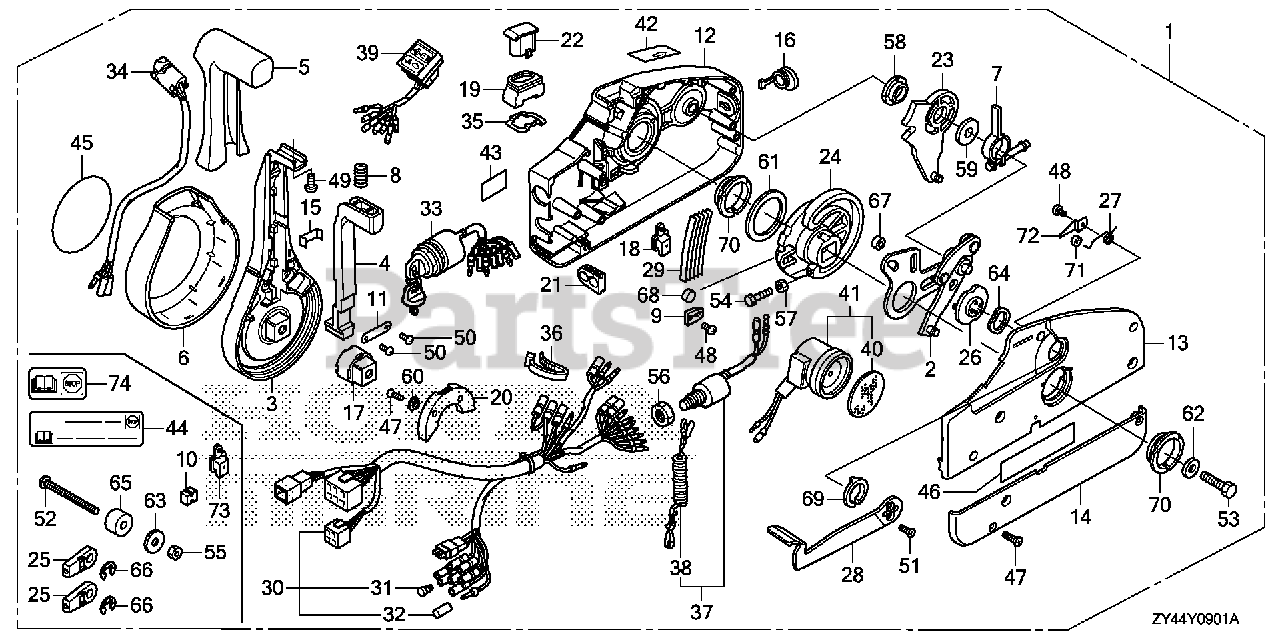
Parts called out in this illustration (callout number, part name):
1	BOX ASSY., REMOTE CONTROL (NHK MEC)
1	BOX ASSY., REMOTE CONTROL (TROLLING CONTROL)(NHK MEC)
2	PLATE ASSY.
3	LEVER, HAND
4	ARM, NEUTRAL LOCK
5	GRIP
6	COVER, LEVER
7	ARM ASSY., BRAKE
8	SPRING (2)
9	CLIP, DETENT
10	SPACER (1) (LOOSE PARTS)
11	BRACKET
12	HOUSING, FR.
13	HOUSING, RR.
14	PANEL, BACK
15	BRACKET, WIRE CLAMP
16	CAP, RUBBER
17	ADJUSTER
18	COVER, POWER TRIM-TILT WIRE
19	SEAL, RUBBER
20	HOLDER, NEUTRAL LOCK
21	GROMMET, WIRE (14)
22	CAP, TROLLING CONTROL SWITCH BLANK
23	GEAR ASSY., SHIFT
24	GEAR, DRIVE
25	TERMINAL, CABLE (LOOSE PARTS)
26	DRUM ASSY., FREE THROTTLE
27	SPRING (1)
28	LEVER, FREE THROTTLE
29	SPRING, DETENT
30	CABLE ASSY., REMOTE CONTROL (B)
31	PLUG, CONNECTOR (INNER)
32	PLUG, CONNECTOR (OUTER)
33	SWITCH ASSY., COMBINATION
34	SWITCH ASSY., POWER TRIM-TILT
35	PLATE, SWITCH
36	BAND, WIRE
37	SWITCH ASSY., EMERGENCY STOP
38	WIRE, EMERGENCY
39	LAMP ASSY., INDICATION
40	PLATE, TURN SIGNAL BUZZER
41	BUZZER, WARNING
42	MARK, FAST IDLE
43	MARK, EMERGENCY STOP (US)
44	MARK, EMERGENCY STOP (US) (LOOSE PARTS)
45	MARK, EMBLEM
46	LABEL, SIGP
47	SCREW (5X18)
48	SCREW (4X6)
49	SCREW (5X10)
50	SCREW (4X10)
51	SCREW (5X12)
52	SCREW (6X90) (LOOSE PARTS)
53	BOLT (8X50)
54	BOLT (5X25)
55	NUT (6MM) (LOOSE PARTS)
56	NUT, HEX. (16MM)
57	NUT (5MM)
58	BEARING (1)
59	WASHER (3)
60	WASHER (4)
61	WASHER (5)
62	WASHER (8MM)
63	WASHER (7) (LOOSE PARTS)
64	WASHER, WAVE
65	SPACER (2) (LOOSE PARTS)
66	E-RING (6MM) (LOOSE PARTS)
67	ROLLER, DRIVE GEAR CAM
68	ROLLER
69	BEARING (2)
70	BEARING (3)
71	ROLLER, FREE THROTTLE
72	CLIP, ROLLER
73	COVER, POWER TRIM-TILT WIRE (LOOSE PARTS)
